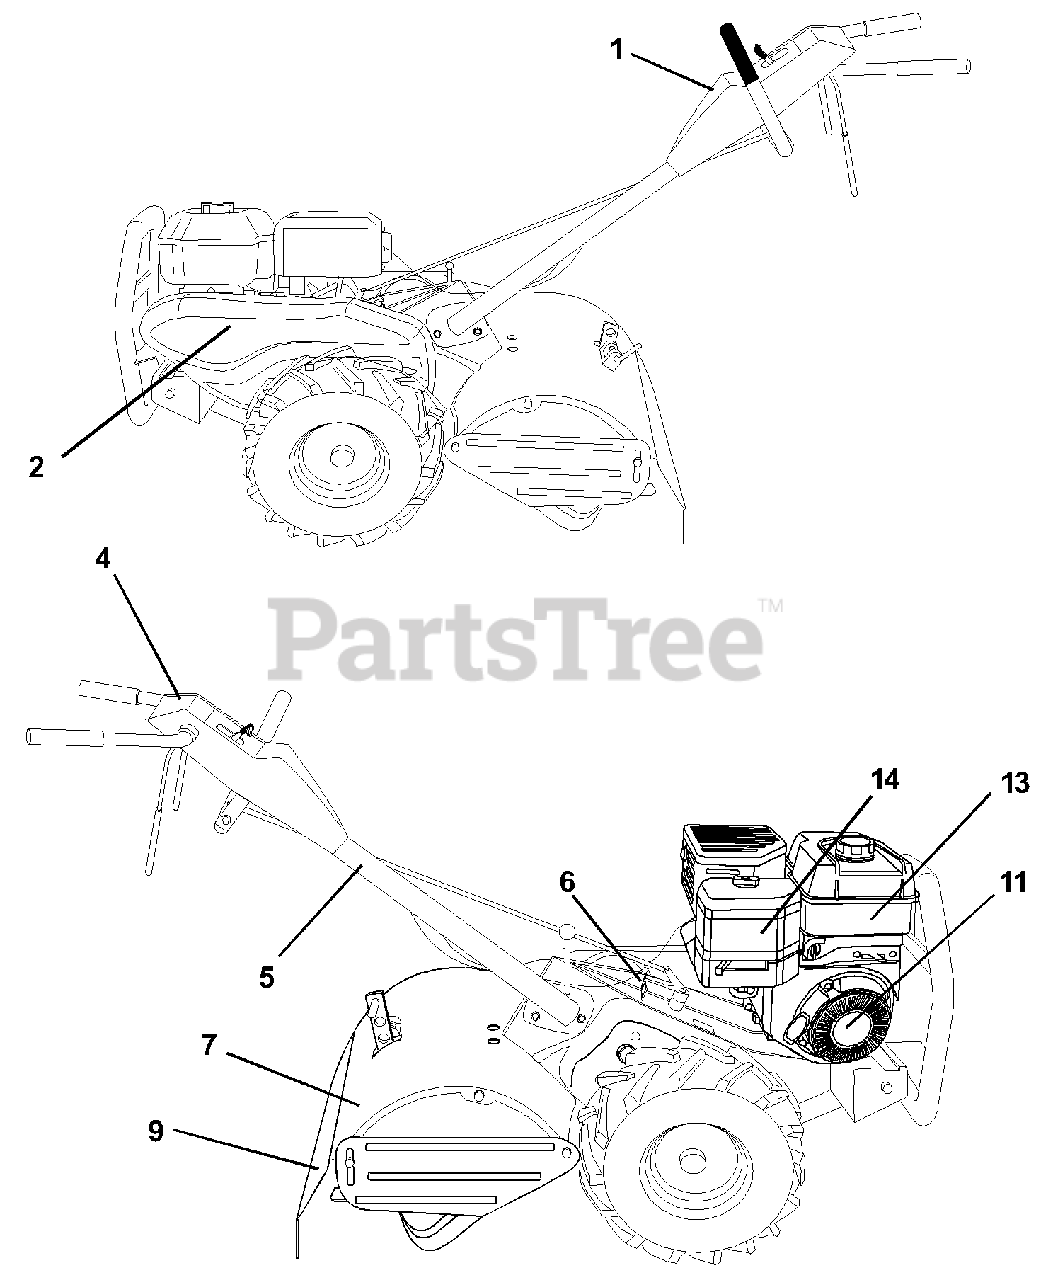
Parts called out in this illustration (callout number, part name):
1	Decal, Logo, CNTRL PNL
2	Decal, Logo, Belt Guard
4	Decal, Instruction, Tilling
5	Decal, Hand Placement
6	Decal, Shift Indicator
7	Decal, Caution
9	Decal, Warning, Rotating Tines
11	Decal, Rewind
13	Decal, B&S Tank
14	Decal, B&S Air Cleaner
